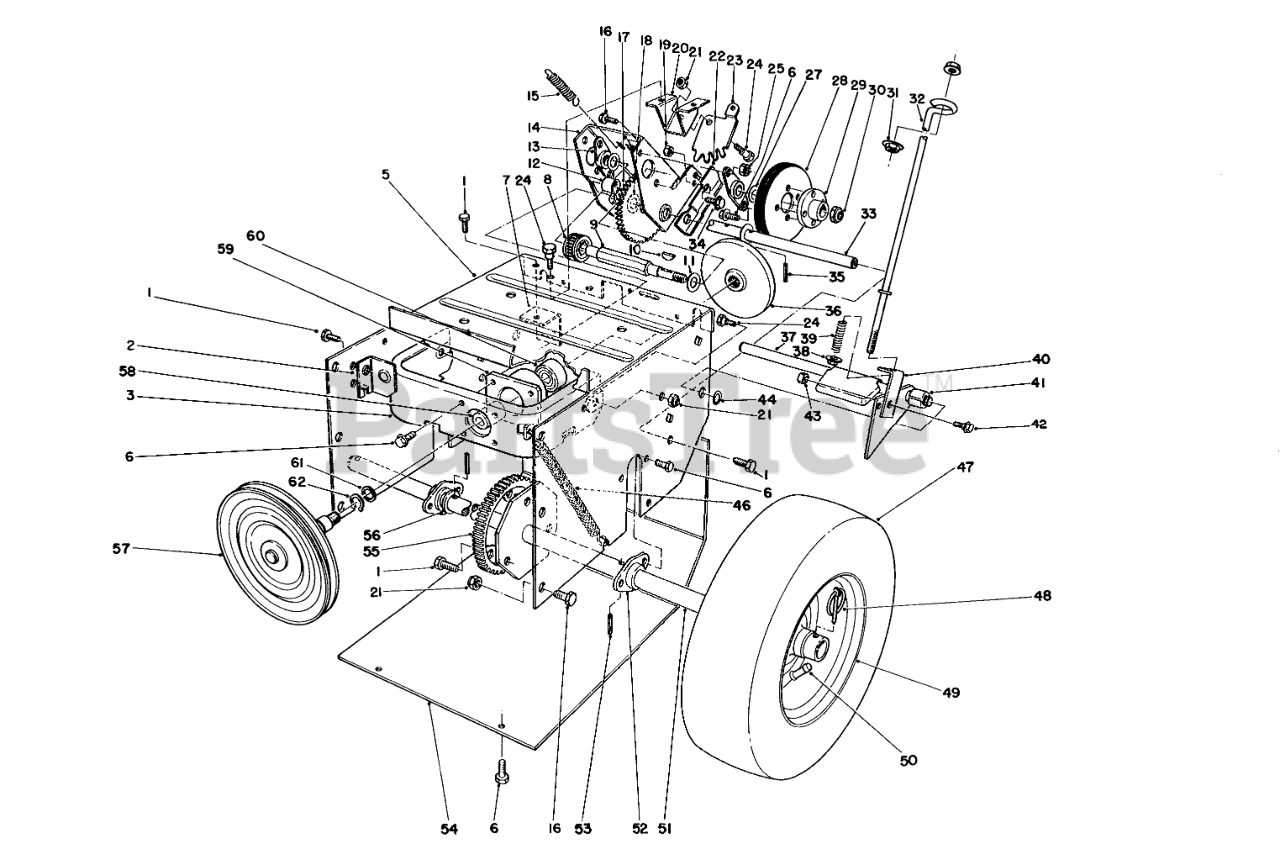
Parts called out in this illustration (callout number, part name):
1	SCREW-HWHTF
2	BRACKET-MOUNT, FRONT
3	Frame-Friction Plate
5	Frame-Traction
6	SCREW-HWH
7	BRACKET-MOUNT, REAR
8	PINION
9	SHAFT-WHEEL, FRICTION
10	KEY-WOODRUFF
11	WASHER-FLAT
12	5/8ID X 1LG BUSHING
13	BEARING-WHEEL, FRICTION
14	BRACKET-SLIDING
15	SPRING-TRACTION
16	SCREW-HH
17	Intermediate Gear & Bushing (Incl. ref. #12)
18	WASHER-SPECIAL
19	NUT-LOCK, NI
20	MOUNT-LEVER
21	NUT-LOCK, NI
22	CAM-RECEIVER
23	GEAR-QUADRANT
24	BOLT-SHOULDER
25	NUT-LOCK, NI
27	WASHER-THRUST
28	WHEEL-FRICTION
29	HUB-WHEEL, FRICTION
30	NUT-LOCK, NI
31	NUT-HF
32	ROD-TRACTION, LOWER
33	SHAFT-PIVOT
34	SCREW-HH
35	PIN-SPRING
36	PLATE-FRICTION
37	Traction Engagement Assy.
38	NUT-HHF
39	SPRING
40	BRACKET-TRACTION
41	SPACER
42	SCREW
43	NUT-LOCK, NI
44	RING-RETAINING
46	SPRING-PLATE, FRICTION
48	PIN-LYNCH
49	RIM-WHEEL
50	TUBE-INNER
51	SHAFT-AXLE
52	BEARING-AXLE
53	PIN-SPRING
54	Bottom Cover
55	GEAR-AXLE
56	WASHER-THRUST
57	PULLEY AND DRIVE ASM
58	BUSHING
59	HUB-FRAME, TRACTION
60	BEARING-BALL
61	Washer-Thrust
62	RING-RETAINING, EXT
